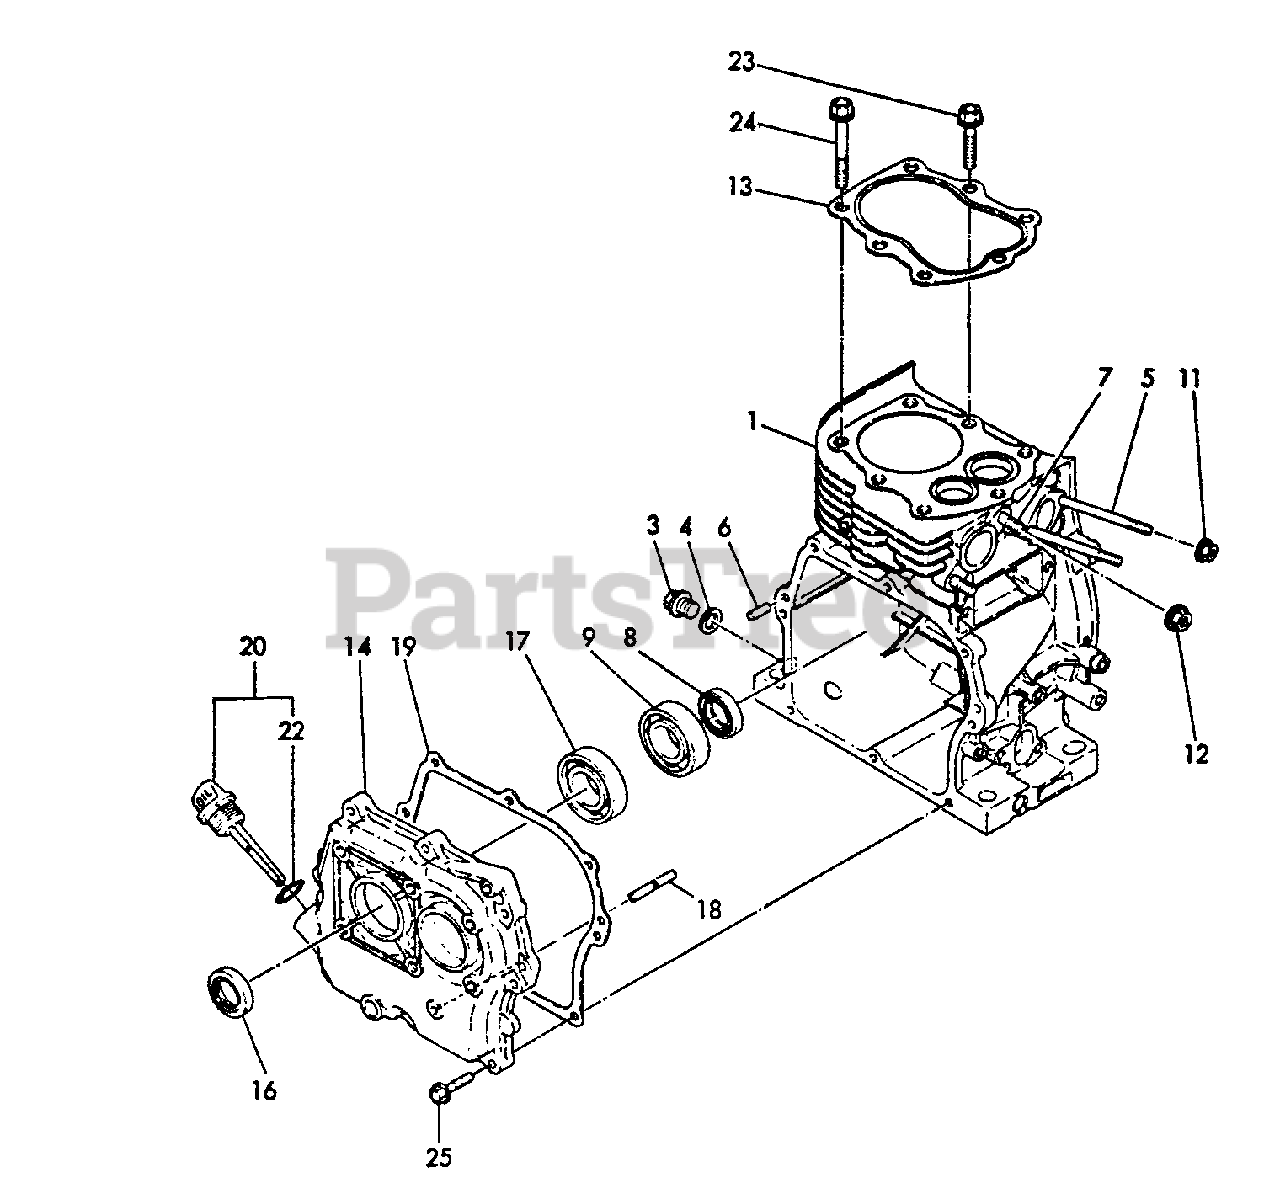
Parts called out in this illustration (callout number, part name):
1	CYLINDER BLOCK SET
3	PLUG, DRAIN
4	GASKET
5	BOLT - 6X70
6	PIN - 6X16
7	STUD - 8X18 -- PLATED
8	SEAL, OIL
9	BEARING, BALL - 6205C3
11	NUT - 6 -- FLANGE
12	NUT - 8
13	GASKET, CYLINDER
14	SIDE COVER ASSY
16	SEAL, OIL
17	BEARING, BALL - 6205C3
18	SHAFT, GOVERNOR
19	GASKET, SIDE COVER
20	CAP ASSY
22	O-RING - 18
23	BOLT - 8X39
24	BOLT - 8X65
25	BOLT - 6X25
